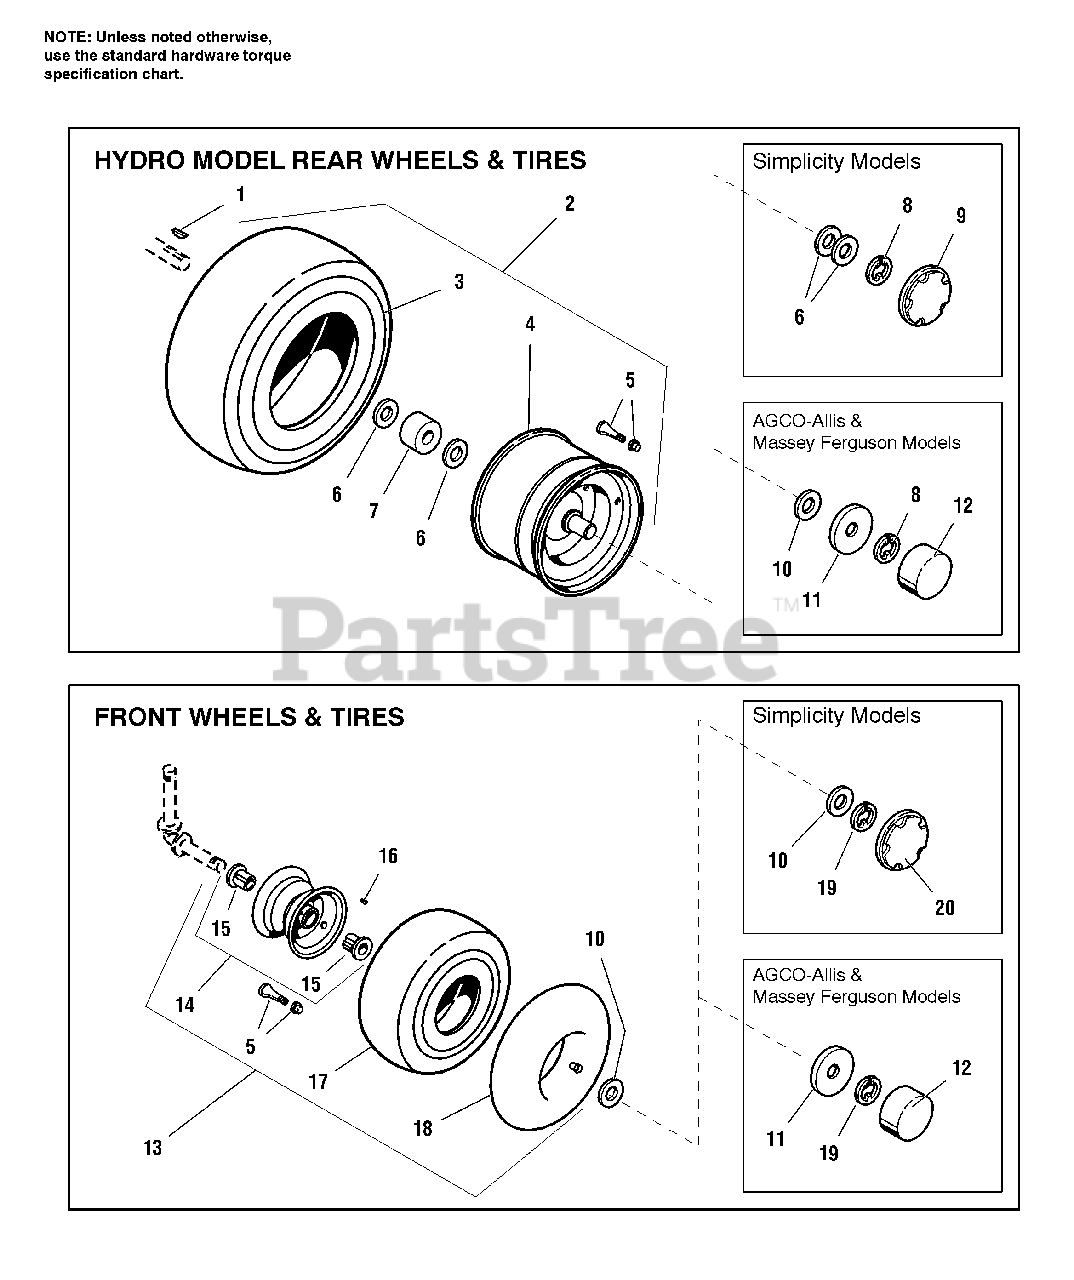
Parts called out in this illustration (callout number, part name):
1	KEY
2	REAR WHEEL & TIRE ASSEMBLY - 16HP Models, 20x8.00-8
2	REAR WHEEL & TIRE ASSEMBLY - 14HP Models, 18x8.50-8
3	TIRE, 18 x 8.50-8" - 14HP Models
3	TIRE, 20 x 8.00-8" - 16HP Models
4	WHEEL, Metallic Gray, 8" , Rear
5	VALVE STEM & CAP
6	WASHER, 3/4 (Qty. 8)
9	HUB CAP, 7-3/4" Black, Rear Scalloped
10	WASHER , 3/4
11	RETAINER, Cap
12	CAP, Axle
13	FRONT WHEEL & TIRE ASSEMBLY - 14HP Models, 15x6.00-6
13	FRONT WHEEL & TIRE ASSEMBLY - 16HP Models, 15x6.50-6
14	WHEEL ASSEMBLY, Metallic Gray, 6" , Front
15	BEARING
16	FITTING, Grease
17	TIRE, 15 x 6.00-6" - 14HP Models
17	TIRE, 15 x 6.50-6" - 16HP Models
18	TUBE, Tire 6", Front
19	KLIPRING, 3/4
20	HUB CAP, 5-3/4, Black, Front Scalloped
